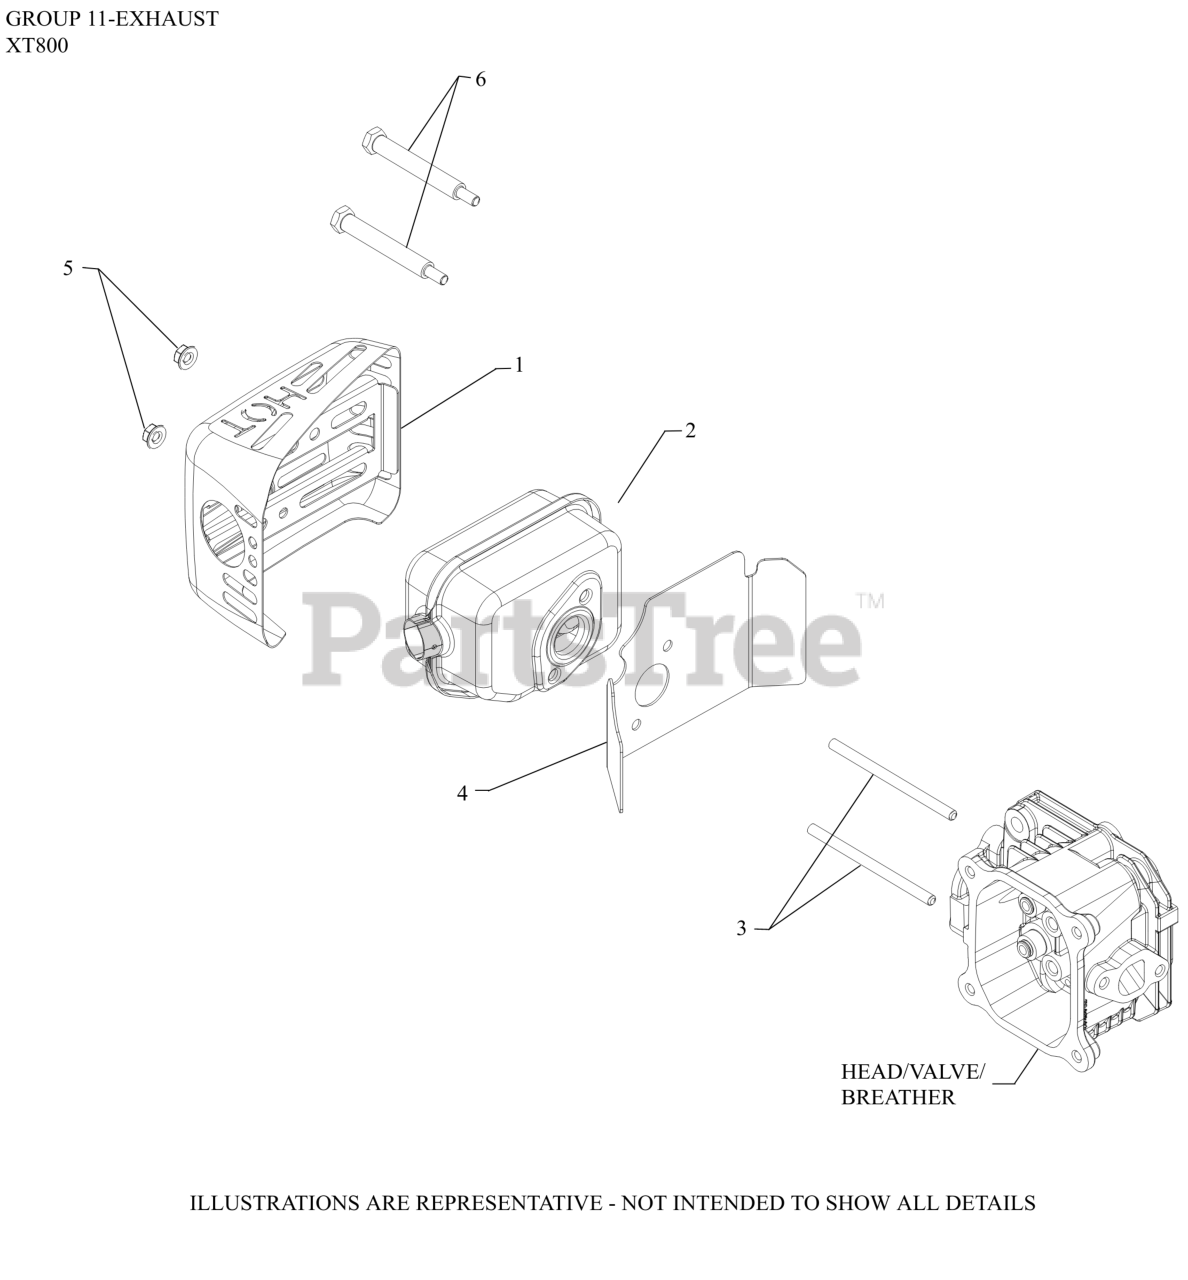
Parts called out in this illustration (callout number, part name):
1	GUARD, MUFFLER
2	KIT, MUFFLER
3	STUD (M6)
4	GASKET, MUFFLER-(#1404155S)
5	NUT, HEX FLANGE LOCK (M6)
